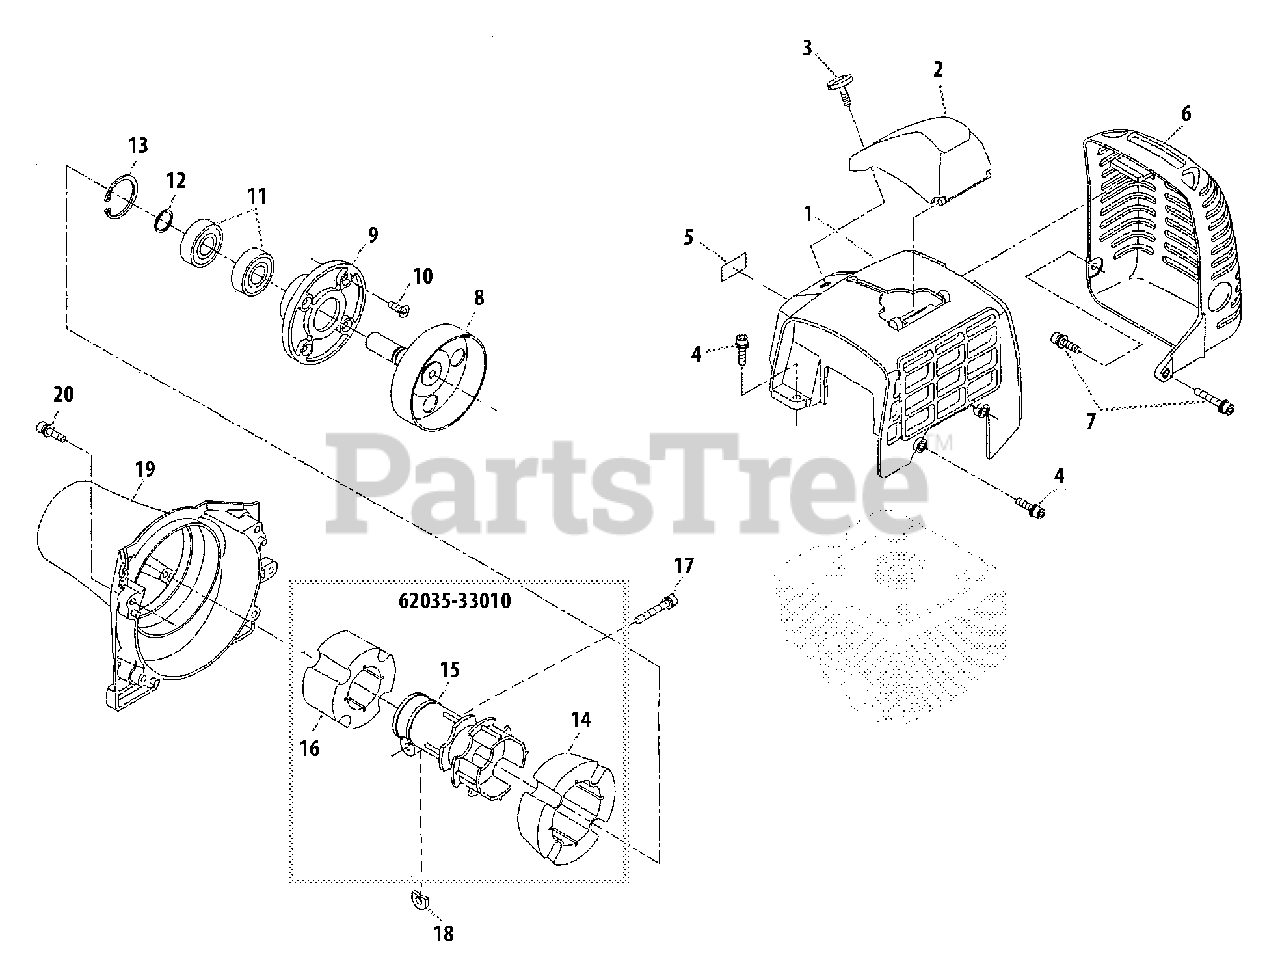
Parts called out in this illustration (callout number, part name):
1	COVER, ENGINE
2	CAP, SPARK PLUG
3	KNOB
4	SCREW - 5X16
5	LABEL
6	COVER, EXHAUST
7	SCREW - 5X16
8	DRUM, CLUTCH
9	COVER, CLUTCH
10	SCREW - 5X16
11	BEARING, BALL - 6202
12	RING, RETAINING
13	RING, RETAINING - 35
14	CUSHION - REAR
15	JOINT
16	CUSHION - FRONT
17	SCREW - 6X28
18	SHIM
19	CASE, FAN
20	SCREW - 5X30
62035-33010	JOINT ASSY
